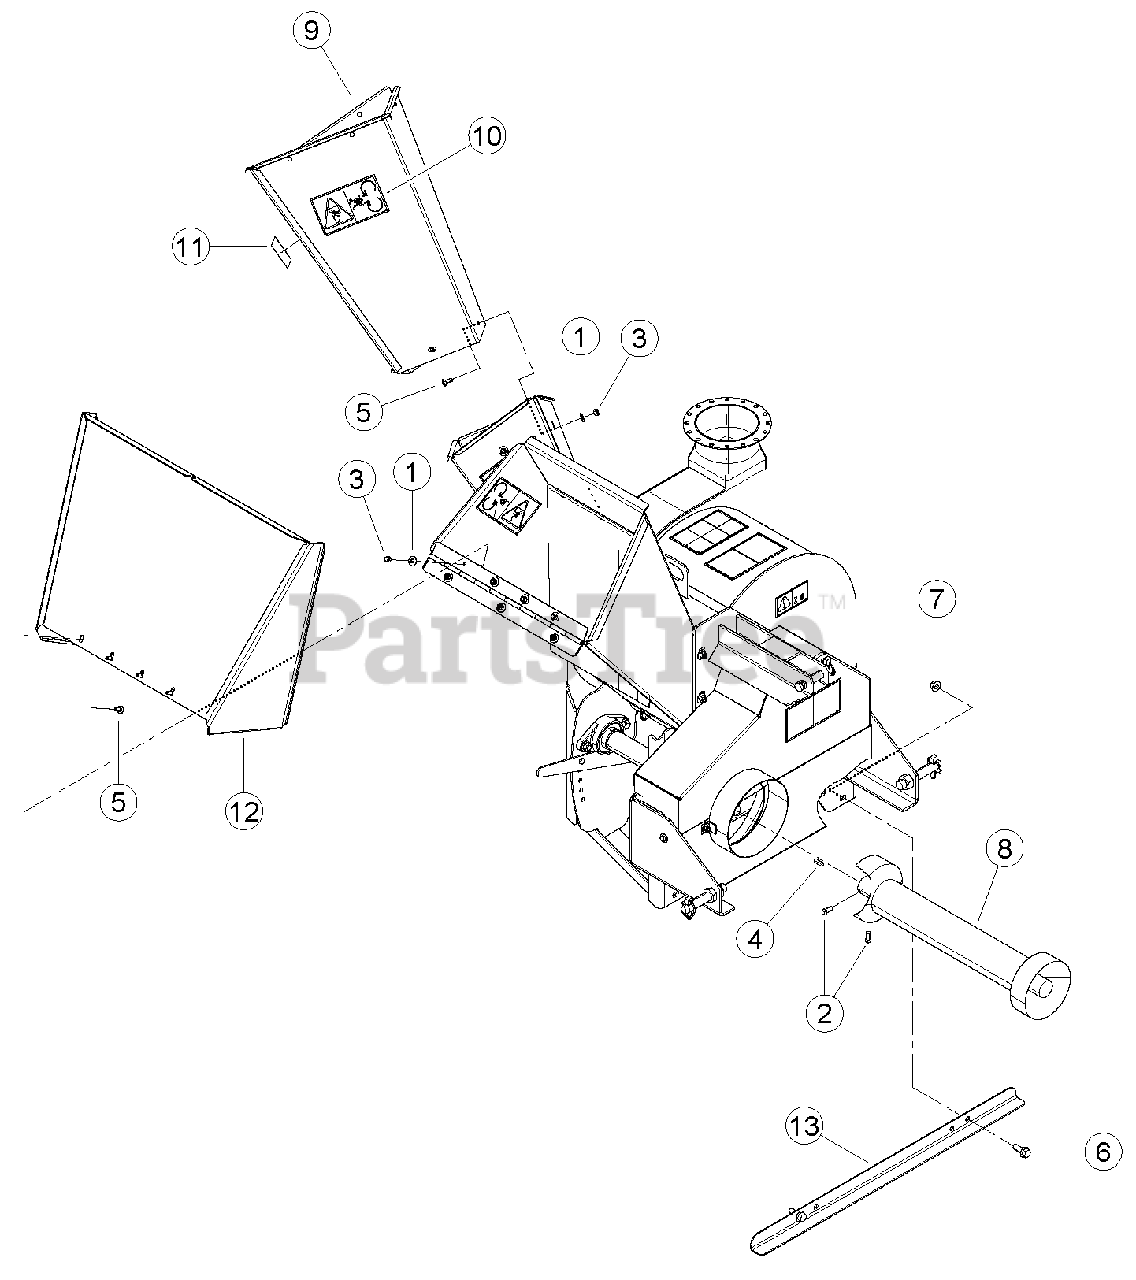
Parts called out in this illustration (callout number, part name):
1	WASHER, 5/16 FLAT ZP
2	SCREW, 3/8 X 3/4 SQ HD SET ZP
3	NUT, 5/16 NE NYLOCK ZP
4	KEY, 1/4 SQUARE X 1 LONG
5	BOLT, 5/16 X 3/4 GR5 CRG NC ZP
6	BOLT, 1/2 X 1-1/4 SERRATED FLANGE
7	NUT, 1/2 SERRATED FLANGE NC ZP
8	DRIVESHAFT, 540 C/S WS
9	ASSEMBLY, COMM. CHUTE EXTENSION, SERVICE PART
10	DECAL, BLADE DANGER ISO
11	DECAL, MUTILINGUAL MANUAL
12	WELDMENT, CHUTE TRAY
13	LEG, C/S SUPPORT
